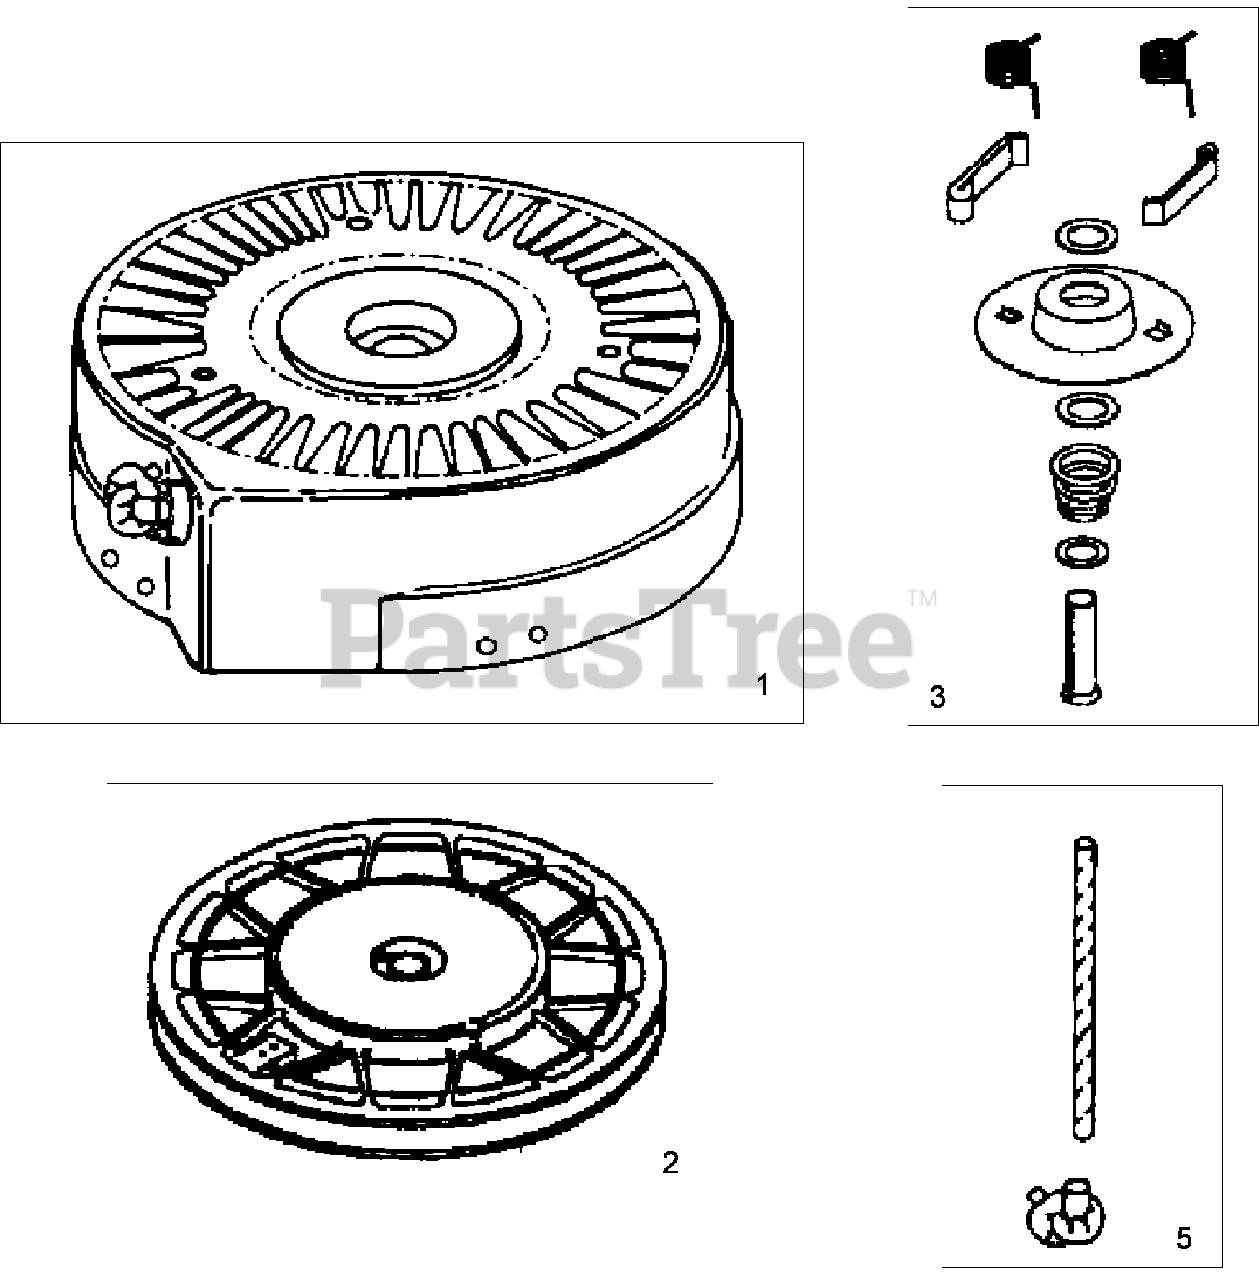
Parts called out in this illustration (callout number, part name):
1	Starter-Recoil (Winter Pulley, Handle not included)
2	Pulley and Rewind Spring ASM
3	Repair Kit
5	Rope-Starter (98 cut to length)
